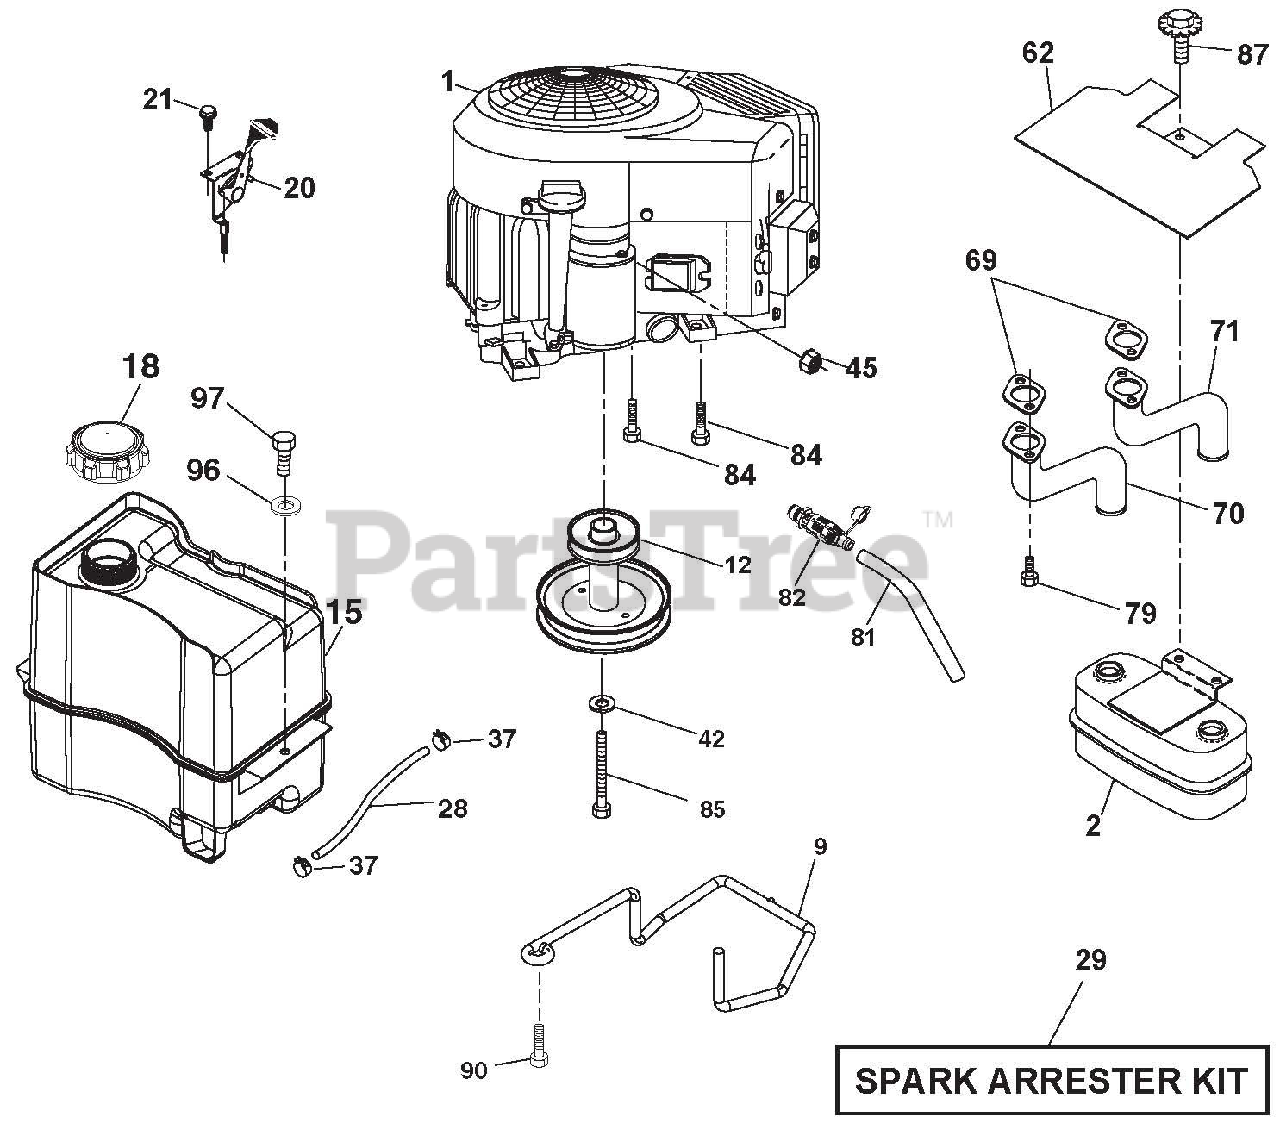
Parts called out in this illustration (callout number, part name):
2	MUFFLER ASM.
9	KEEPER BELT ENGINE
12	PULLEY.ENGINE.5.0.P.D.
15	TANK FUEL
18	CAP FUEL
20	CONTROL THROTTLE/CHOKE
28	LINE.FUEL.20"
29	KIT.SPARK ARRESTOR(392390 B&S)
37	CLAMP.HOSE.BLK.
42	WASHER.LOCK.HVY HLCL.SPR.7/16
45	Nut, Keps Hex 1/4-20 unc
62	SHIELD.HEAT.MUFFLER.
69	GASKET MUFFLER
70	EXHAUST TUBE LH
71	EXHAUST TUBE RH
79	SCREW SOCKET HEAD 5/16-18 X 1
81	TUBE.DRAIN.OIL.EASY
82	VALVE OIL DRAIN
84	Screw 3/8-16 x <
85	BOLT.HEX.7/16-20X4XGR5-1.5THR.
87	BOLT.5/16-18 UNC X 1 W/SEMS.BL
90	SCREW.3/8-16X1.SMGML.TAP/R.BLK
96	WASHER.9/32 X 7/8 X 16GA.
97	SCREW.HEXWSH.THDROL.1/4-20X3/4
